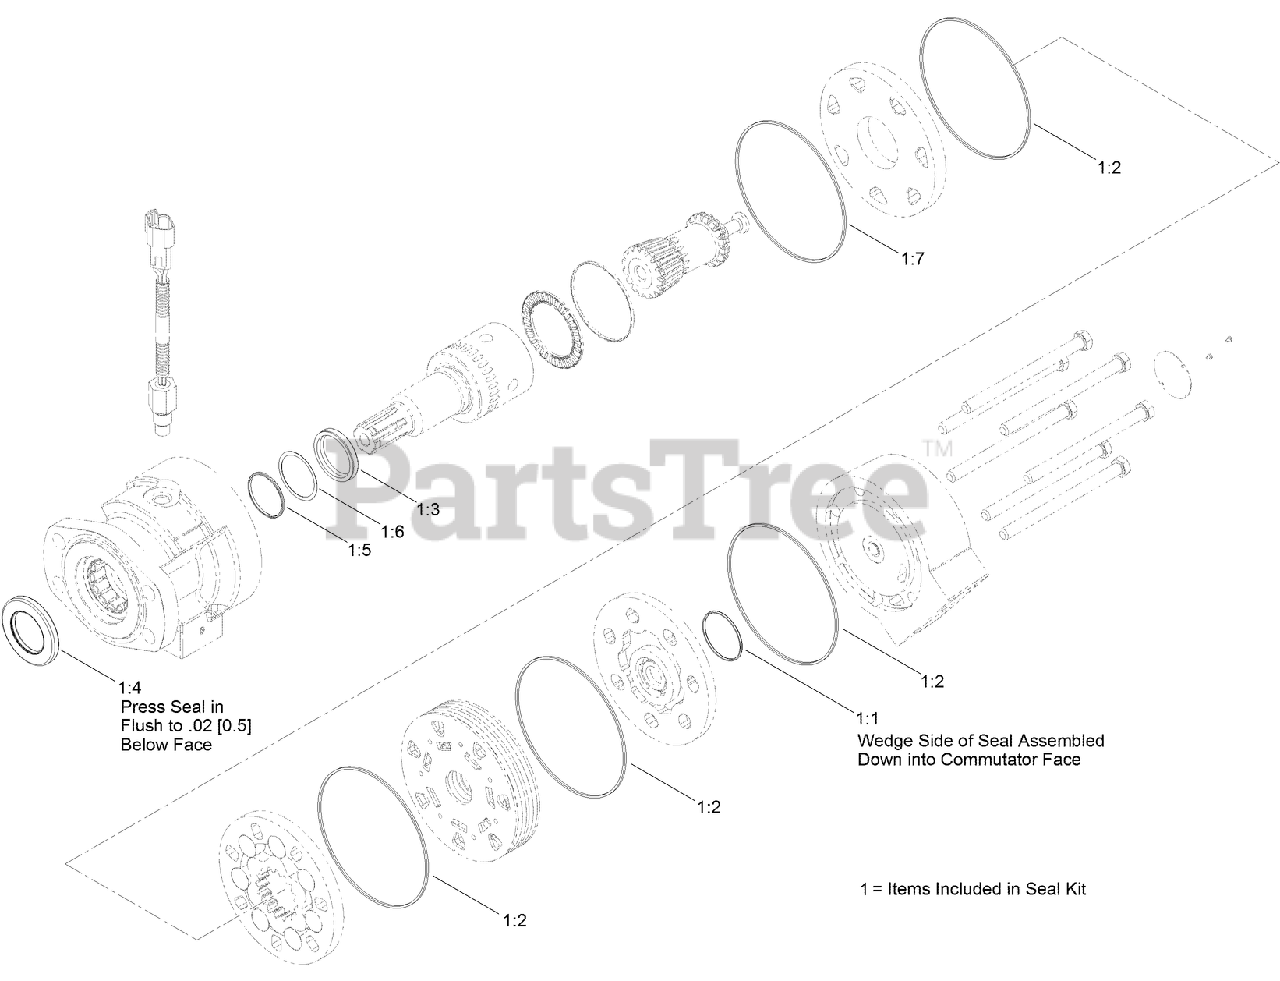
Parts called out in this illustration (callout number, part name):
1	SEAL KIT
1:1	Deck ASM
1:2	Deck ASM
1:3	SEAL-Shaft
1:4	Deck ASM
1:5	Ring-Back Up
1:6	Washer-Back Up
1:7	SEAL-HOUSING
